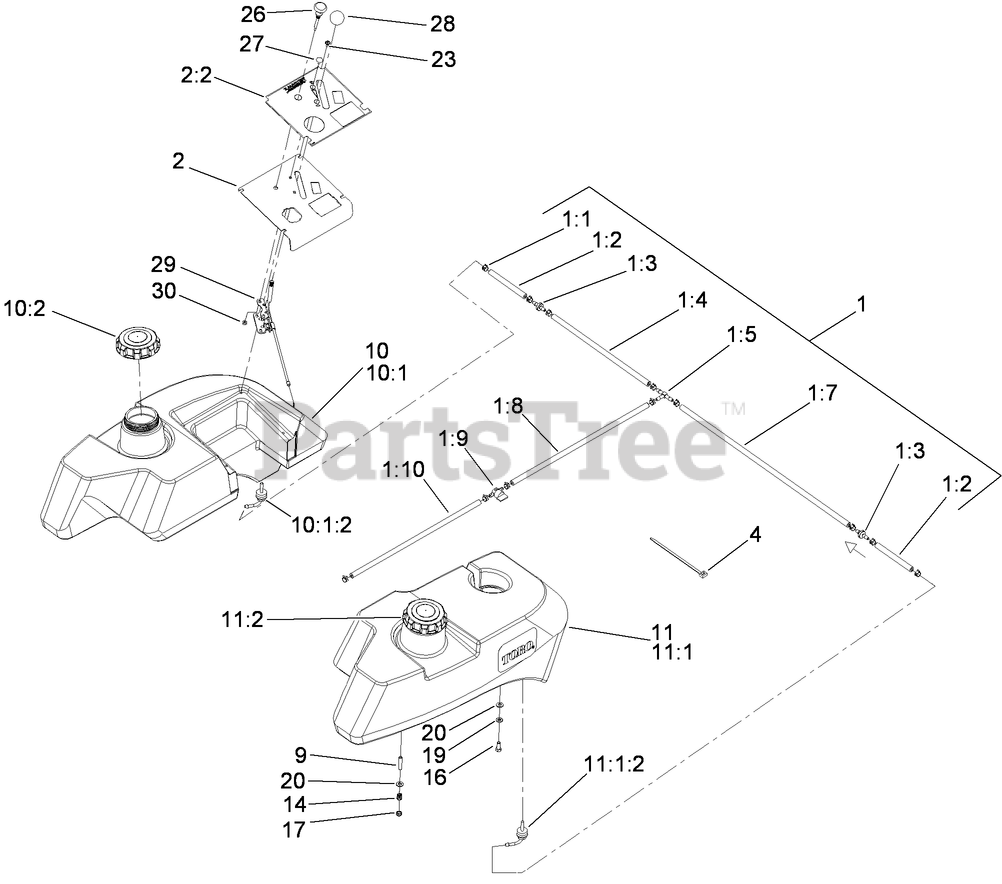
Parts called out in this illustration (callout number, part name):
1	FUEL LINE ASM
1:1	CLAMP-HOSE
1:2	HOSE-FUEL
1:3	VALVE-CHECK, FUEL
1:4	HOSE-FUEL
1:5	FITTING-TEE, BARBED
1:7	HOSE-FUEL
1:8	HOSE-FUEL
1:9	VALVE-FUEL
1:10	HOSE-FUEL
2	CONTROL PANEL ASM
2:2	DECAL-PANEL, CONTROL
4	TIE-PLASTIC
10	LH FUEL TANK KIT
10:1	LH FUEL TANK ASM
10:1:2	FITTING-FUEL, BULKHEAD
10:2	CAP-FUEL, GAS
11	RH FUEL TANK KIT
11:1	RH FUEL TANK ASM
11:1:2	FITTING-FUEL, BULKHEAD
11:2	CAP-FUEL, GAS
14	SPRING-TANK, FUEL
16	SCREW-HH
17	NUT-LOCK, NI
19	WASHER-LOCK
20	WASHER-PLAIN
23	SCREW-PPH
26	Control-Choke, Push / Pull
27	BOLT-CARR
28	KNOB-BALL
29	CABLE-THROTTLE
30	NUT-LOCK, NI
